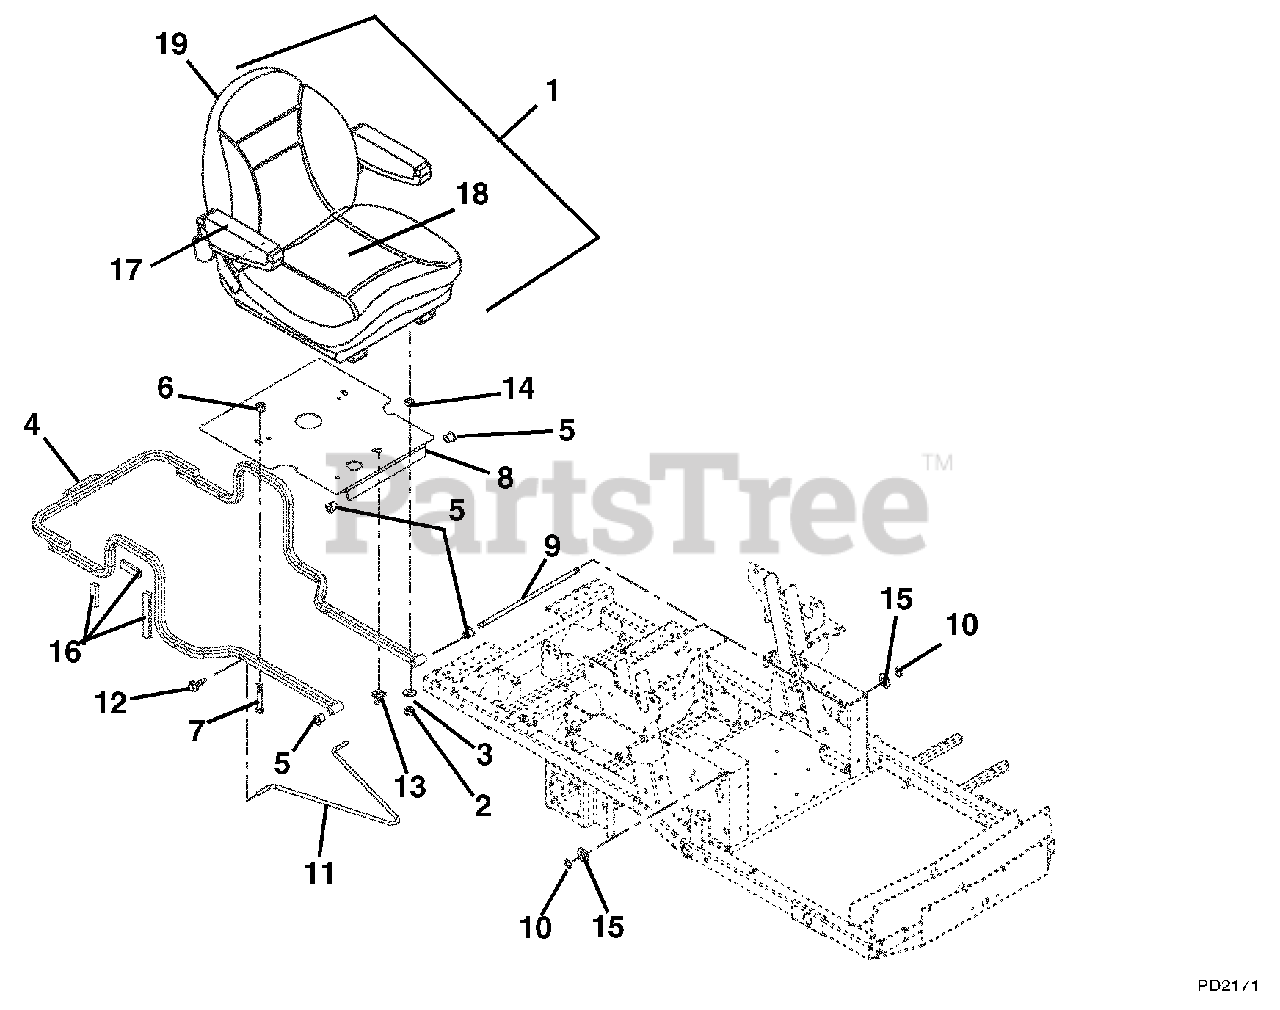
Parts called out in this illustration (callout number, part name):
1	Seat-Suspension
2	Nut-Locking-Nylon M8-1.25
3	Washer-Flat-Steel .38 x .875 x .083
4	Weldment, Hood Frame
5	Bushing-Flange .515 x .750 x .745 x 1.00
6	Nut-Locking-Top-Flange .38-16
7	Bolt-Rib Neck .38-16 x 1.50
8	Weldment, Seat Pivot Mount
9	Rod-Seat Frame Pivot
10	Ring-Retaining-External .500 x .050
11	Rod-Prop
12	Screw-Tapping .25-20 x .50 Hex Washer Head
14	Bushing-Sleeve .377 x .624 x .235
15	Washer-Flat-Steel .531 x 1.06 x .095
16	Tape, VHB
17	Kit-Arm Pad (1 per bag)
18	Kit, Seat Cushion
19	Kit, Back Cushion
